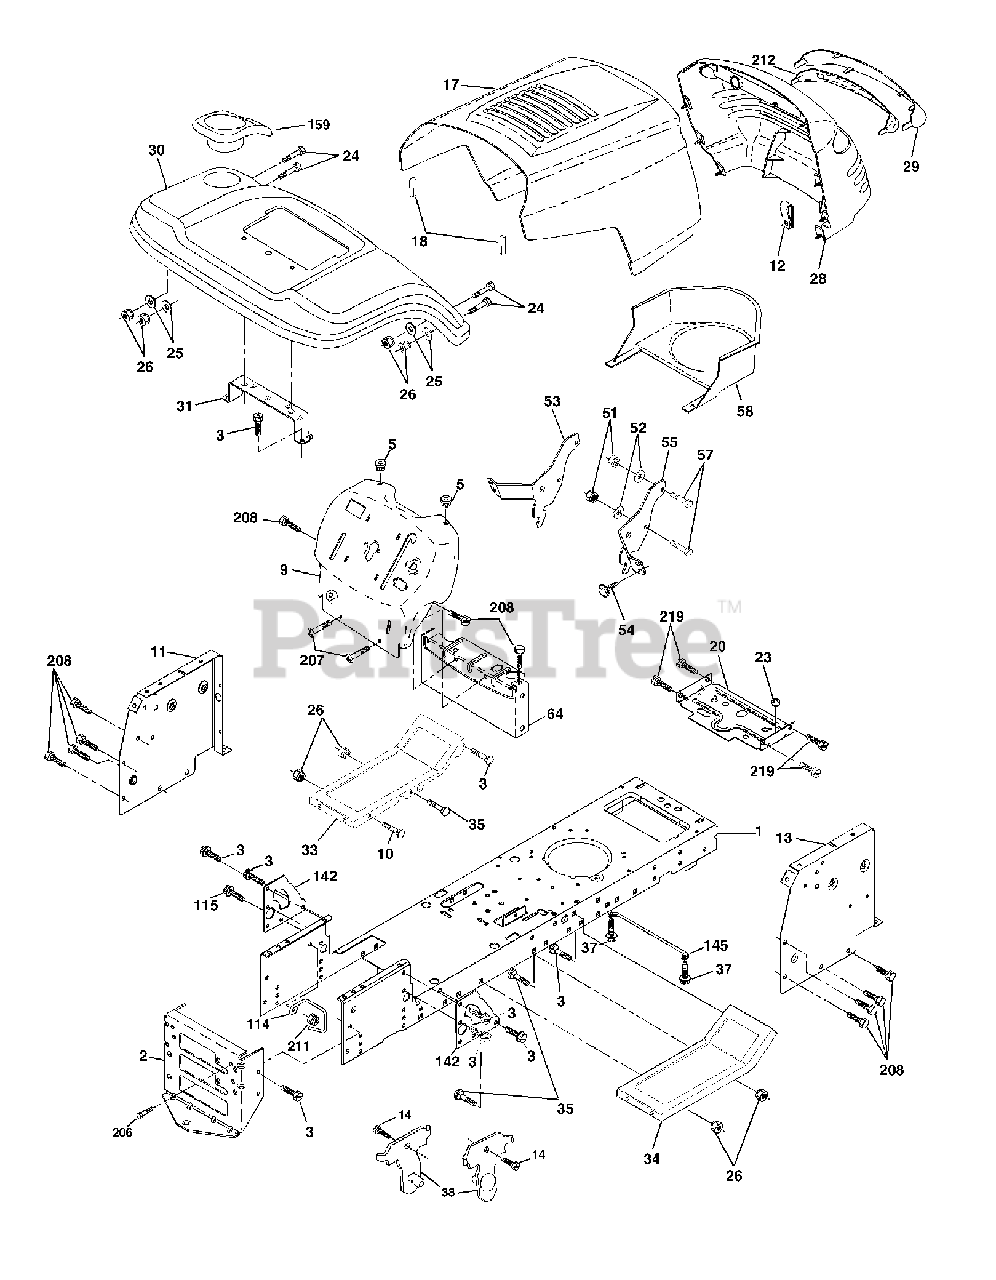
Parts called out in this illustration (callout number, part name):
1	CHASSIS STAMPING
2	DRAWBAR, 12GA
5	BUMPER.RUBBER.HOOD
9	LENS.LASER.LT,BAR.BLACK
11	PANEL.DASH.LH.LTX
13	PANEL ASM, DASH RH
14	SCREW LT
20	PLATE MTG.BATTERY/FUEL TANK
23	GROMMET T
25	WASHER
26	NUT
28	GRILLE LT/PL
29	LENS
31	BRACKET FENDER
33	FOOTREST.LH.BLACK
34	FOOTREST.RH.BLACK
37	SCREW LT
38	BRACKET.ASM.PIVOT.MOWER.REAR
51	LOCKNUT.NYLOC.1/4-20
53	BRACKET.GRILLE.LH
54	SCREW.HEX.WS.HD.8-18 X 7/8
58	AIR DUCT P/L/LT
64	DASH LOWER
115	SCREW.3/8-16
142	PLATE REINFORCEMENT
159	CUPHOLDER.BLACK
206	SHOULDER BOLT 5/16-18TT
207	SCREW, 5/16-18 X 1/2
208	SCREW 3/8-16X1/2
211	Flange Hex Lock Nut, 3/8-16
212	REPL BY 532 1745-03
219	SCREW
